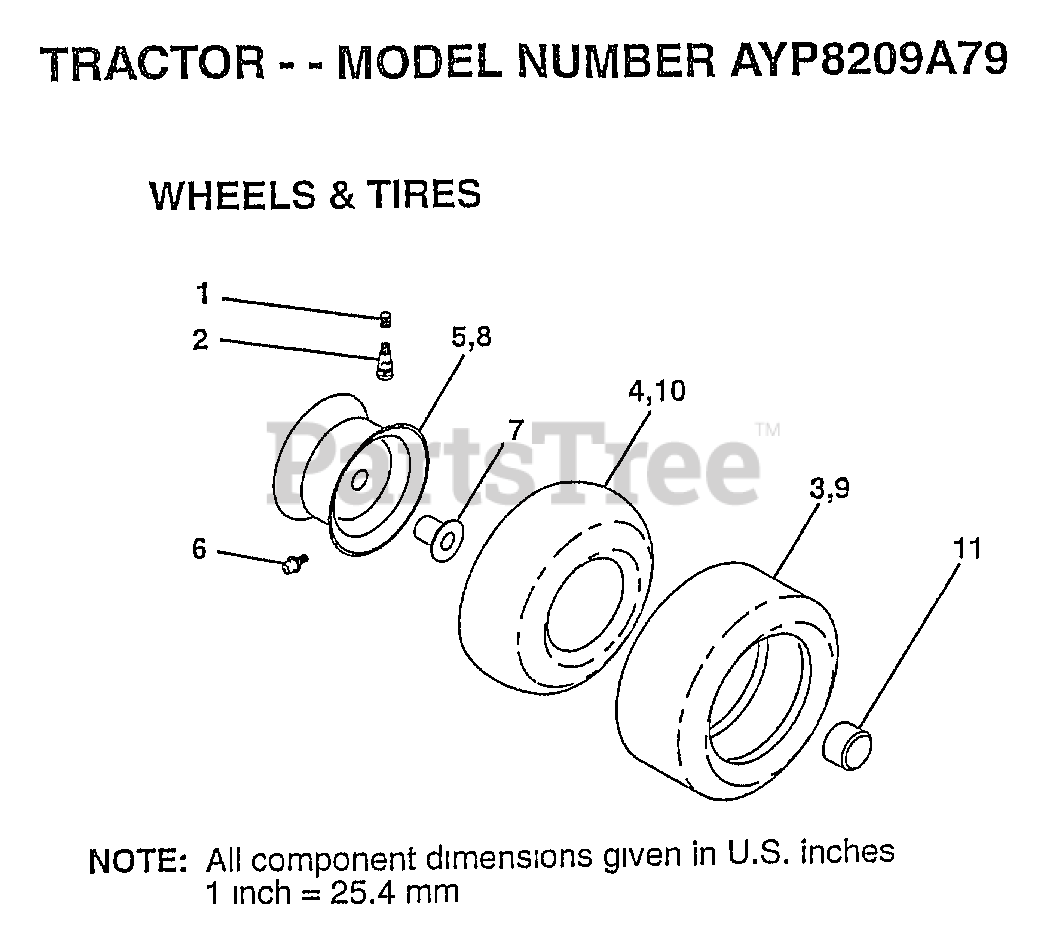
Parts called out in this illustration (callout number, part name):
1	VALVE CAP
2	VALVE STEM LT
4	TUBE.16X6.5/7.5-8
5	"RIM ASM 8"" FRT"
6	FITTING LT
7	"FLANGE, BEARING"
8	"RIM ASM 12"" REAR"
10	TUBE.23X8/10-12
11	HUB CAP
